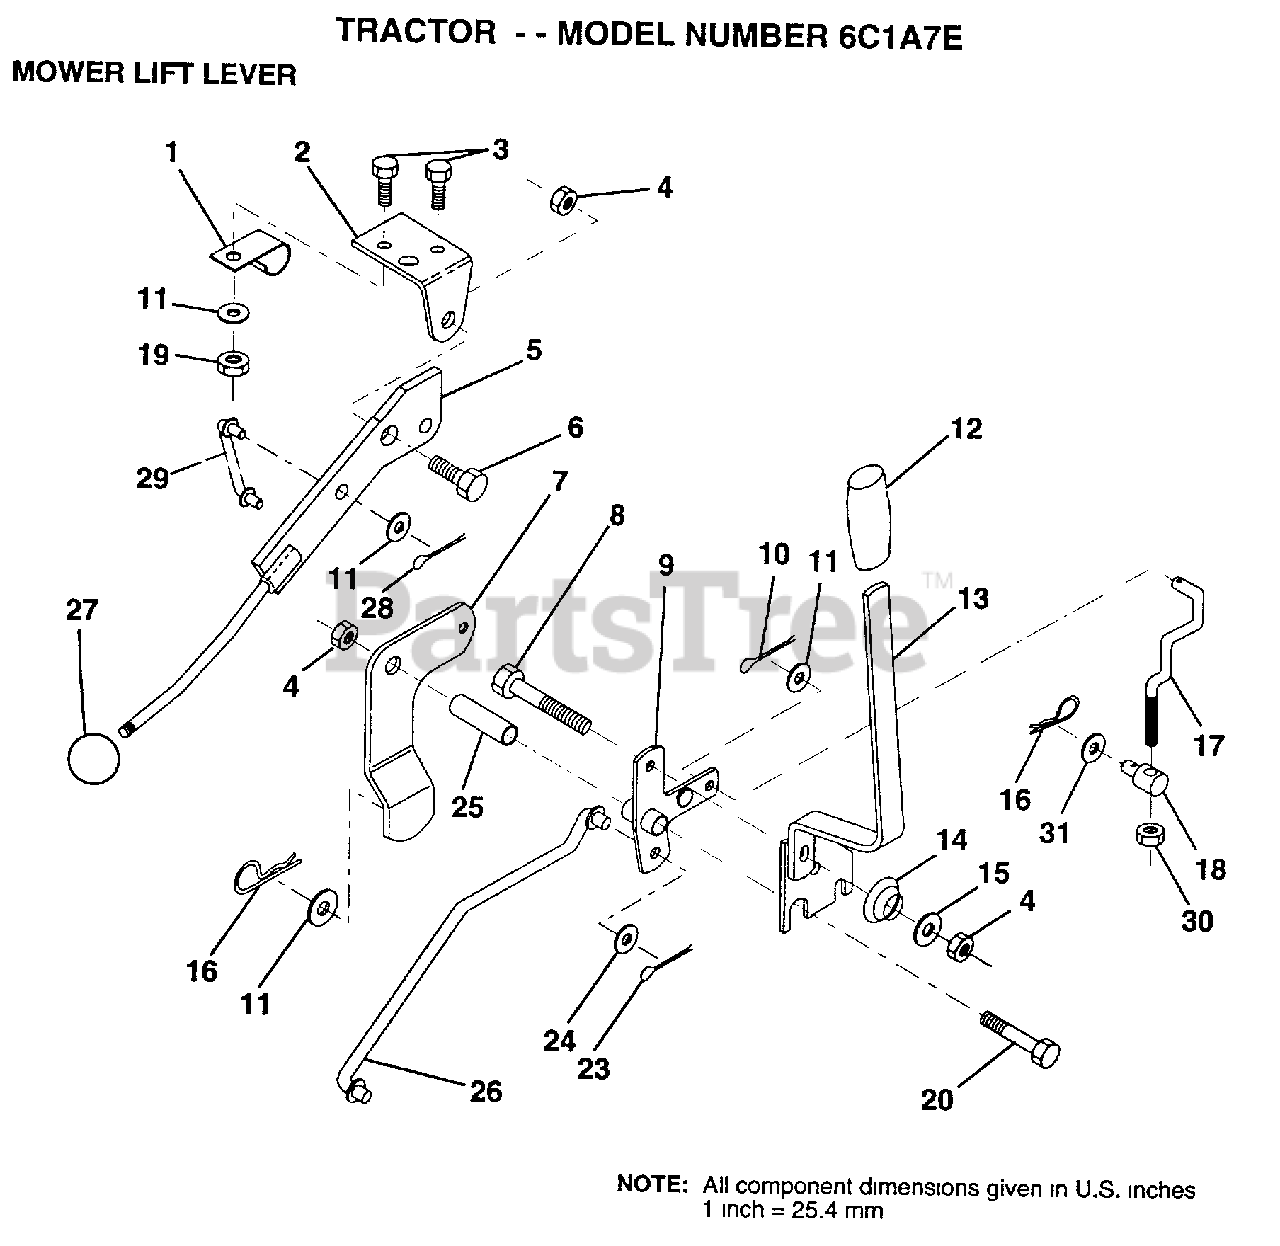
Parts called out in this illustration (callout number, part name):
1	"CLIP,INSULATOR"
2	BRKT CLUTCH
3	BOLT HXHD FIN
5	LEVER.ASM.CLUTCH
6	"BOLT, SHOULDER LT"
7	MWR CLUTCH ARM AS
8	BOLT
9	"BELLCRANK,LIFT"
10	COTTER PIN
11	WASHER HYT
13	HANDLE.ASM.LIFT
14	SPRING COMPRESSIO
15	WASHER T
16	SPRING.RETAINER
17	"LINK,LIFT FRT"
18	TRUNION ADJ
20	BOLT
23	PIN COTTER 1/8
25	TUBE SPACER
26	ROD LIFT MOWER
27	KNOB T(3/8 HOLE)
29	CLUTCH LINK
30	NUT
31	WASHER
